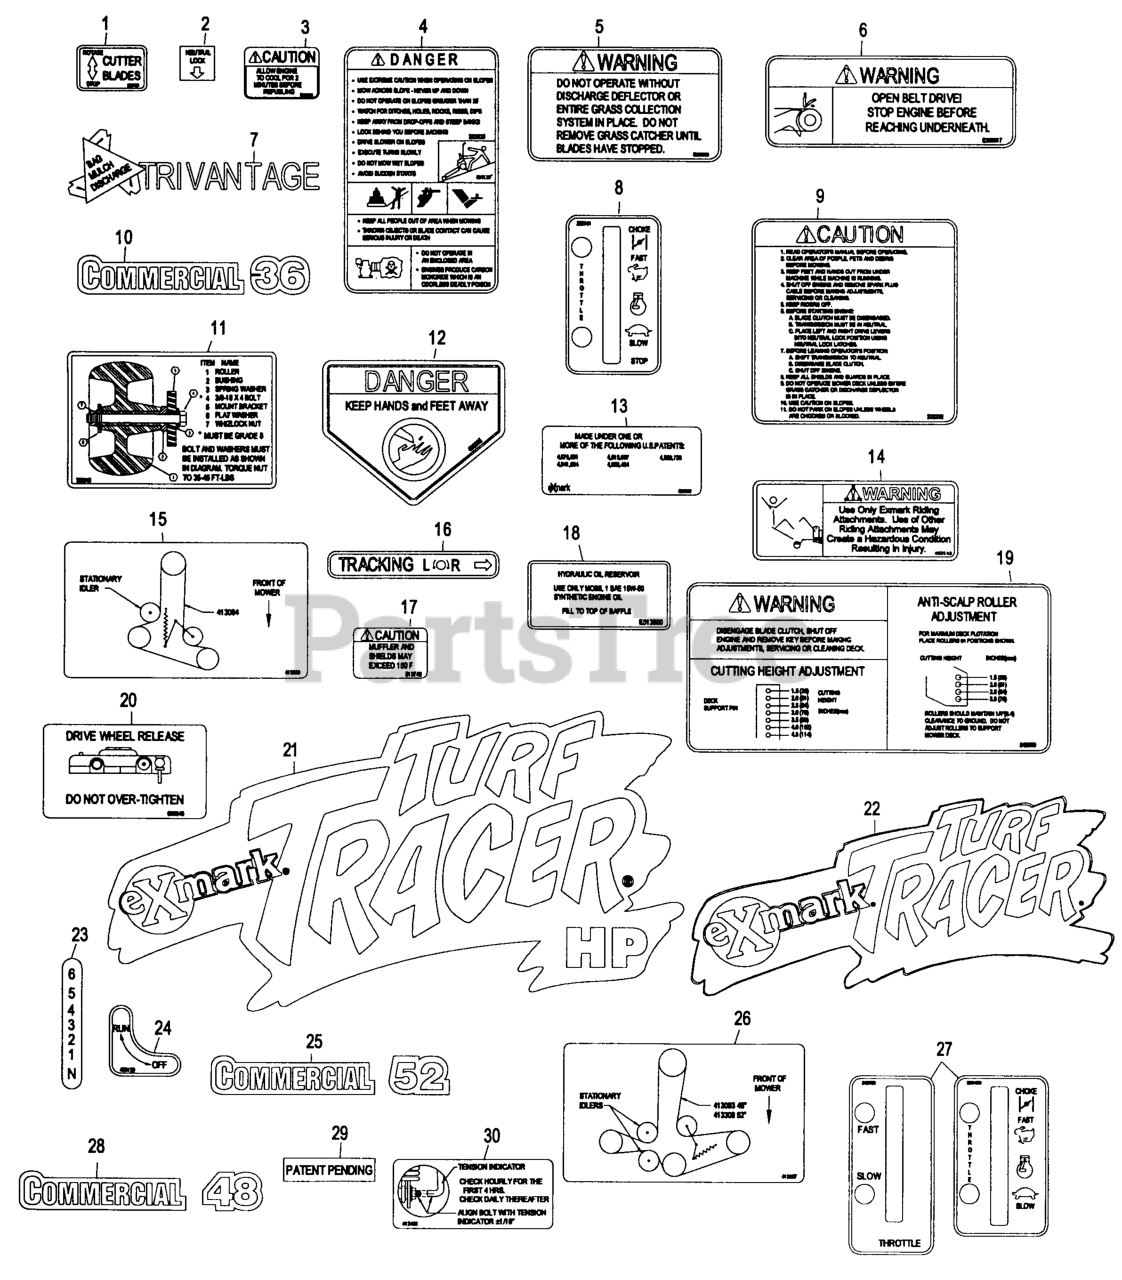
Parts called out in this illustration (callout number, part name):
1	DECAL,CUTTER BLADE
2	DECAL,NEUTRAL LOCK
5	DECAL-WARNING, DISCHARGE
6	DECAL,BELT DRIVE
9	DECAL,INSTRUCTIONAL
10	DECAL,COMMERCIAL 36
11	DECAL,ROLLER MOUNTING
12	DECAL-DANGER
14	DECAL,SULKY WARNING
15	DECAL,BELT ROUTING
16	DECAL,TRACKING ADJUST
18	DECAL,HYD TANK
20	DECAL,DRIVE RELEASE
23	DECAL - SHIFTER
25	DECAL,COMMERCIAL 52
26	DECAL,BELT ROUTING
28	DECAL,COMMERCIAL 48
29	Decal, Patent Pending
30	DECAL,INDICATOR
